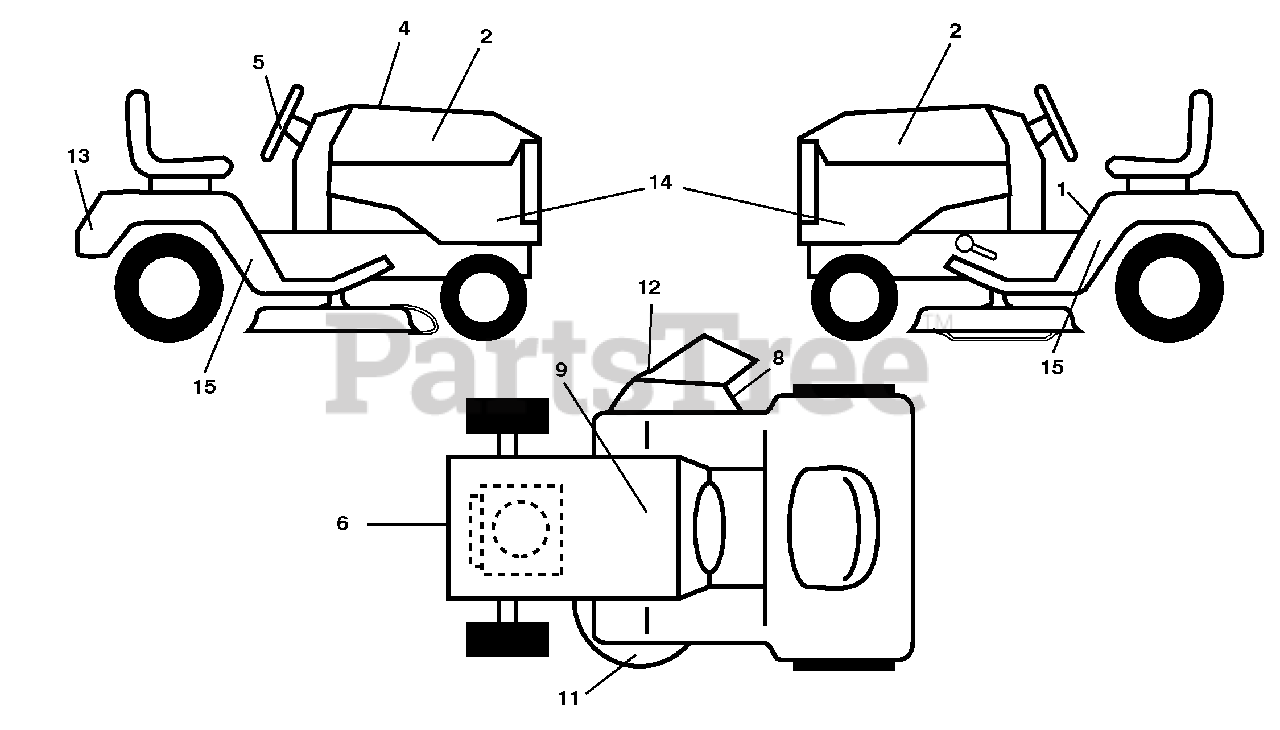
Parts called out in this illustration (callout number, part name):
1	Decal, Operator's
2	Decal, Hood RH/LH
4	Decal, Replacement
5	Decal, Strg Whl
6	Decal, Engine HP
8	Decal, Mower Sch.
9	Decal, Battery Dnge/Poi
11	Decal, Mower Caution
12	Decal, Mower Warning Keep Hand Away
13	Decal, Fender
14	Decal, Panel SD
15	Decal, Fender SD LH/RH
16	Decal, Fender SD RH
16	Decal, Bypass
16	Pad, Footrest, RH
16	Pad, Footrest, LH
16	Manual, Operator's (Eng & French)
16	Manual, Operator's (Spanish)
16	Manual, Parts
